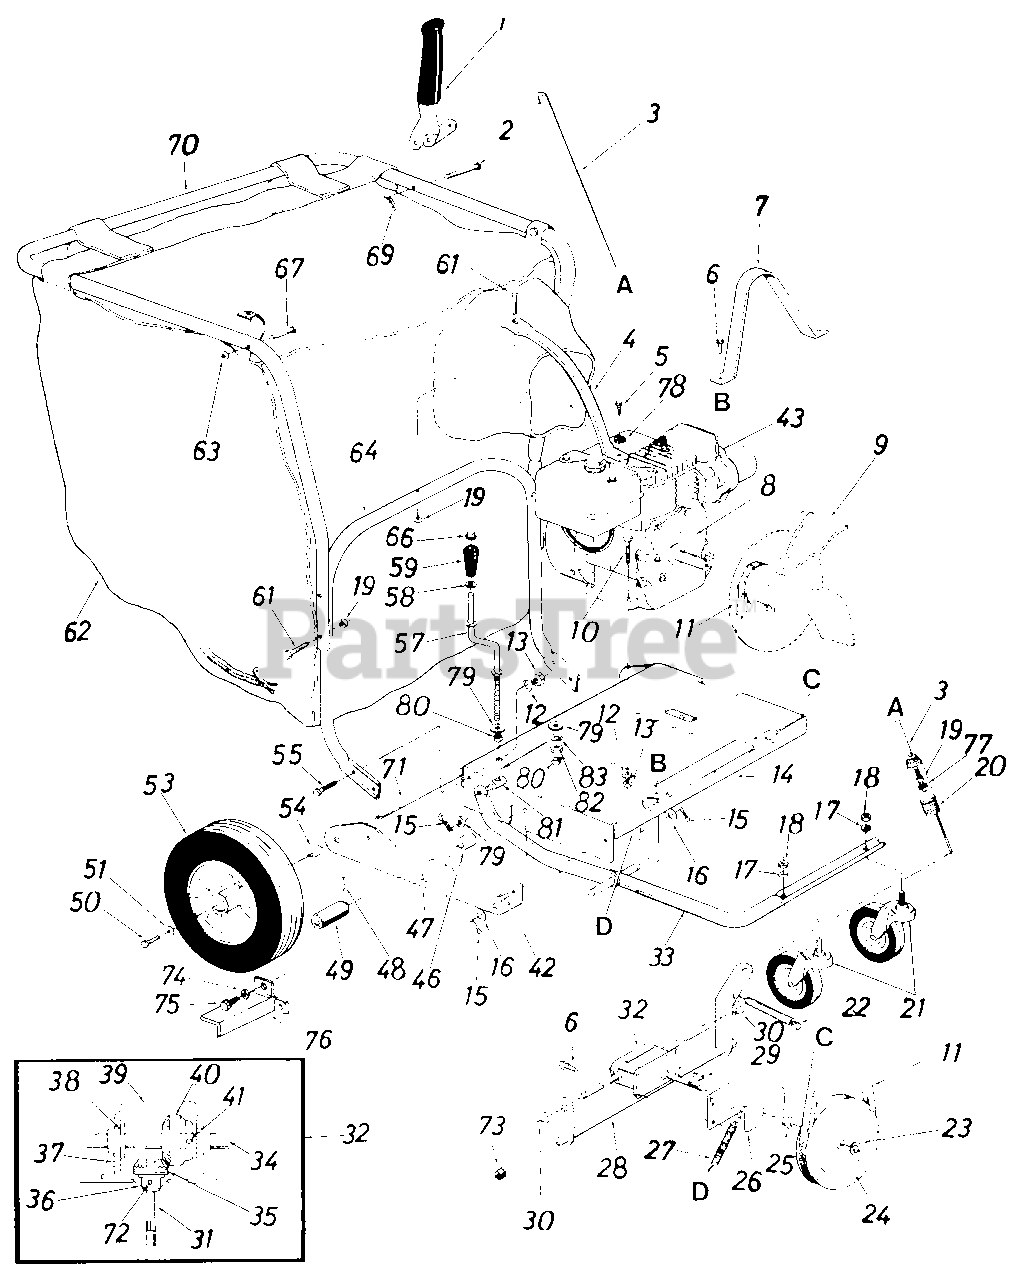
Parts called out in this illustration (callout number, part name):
1	Clutch Grip Ass y.
2	Clevis Pin .375" Dia. x 1 88"
3	Clutch Rod 32" Lg.
4	Handle Brace (Painted)
5	Part of Engine
6	Hex Wash. Hd. AB-Tap Scr. 1/4" x .62" Lg
11	"V-Belt
12	L-Wash. 5/16" I.D.
13	Hex Nut 5/16-18 Thd.*
16	Fl-Wash. .63" I.D. x 1.25" O.D.
17	L-Wash. 1/2" I.D.
18	Hex Nut 1/2-13 Thd.*
19	Hex Cent. L-Nut 1/4-20 Thd.
20	Extension Spring .78" O.D. x .75" Lg.
21	Swivel Caster Wheel 5" Dia. x 1 .25"
22	Extension Spring .38" O.D. x 7.50" Lg
23	Snap"E"-Ring.50" Dia. Shaft
24	"V"-Pulley 5/8" x 6.50" O.D.
25	Flange Bearing .502" I.D.
28	Clutch Bracket Assy zt
29	#2 Woodruff Key 3/32" Dia. x .81 " Lg.
30	Hex Flange Bearing Bronze .625" I.D.
31	Pinion Shaft .50" Dia. x 5"
32	Gear Box Ass'y. Comp.
35	Bevel Gear .50" I.D. x 14 Teeth
36	Flange Bearing .503" I.D.
37	Gear Box
38	Flange Bearing .630" I.D.
39	Gear Box Covert
40	Bevel Gear .62" I.D. x 28 Teeth
41	Spring Pin Spiral 3/16" Dia. x 1.25" Lg.
42	Hex Wash. Hd. AB-Tap Scr. 5/16" x.75" Lg.
43	Engine
46	Spacer.63" I.D. x .88" O.D. x .56" Lg.
49	Drive Piniont
50	Hex Locking Bolt 5/16-24 x .62" Lg.
51	Fl-Wash. .34" I.D. x .87" O.D.
53	Wheel Ass'y. Comp. 12" x 3"
54	Spacer .63" I.D. x 1.0" O.D. x .94" Lg.
55	Hex Bolt 5/16-18 x .75" Lg.
57	Height Adjustment Crank
58	Fl-Wash. .385" I.D. x .62" O.D.
59	Crank Knob
61	Hex Bolt 1/4-20 x 1.75" Lg.
62	Vacuum Bag-Felt
63	Push Speed Nut .25" Dia. Stud
66	Push Nut 3/8" Dia.
67	Stud Pin .250" Dia. x 1.75"
69	Internal Cotter Pin 3/8" Dia.
70	Upper Handle (Painted)
72	Spring Roll Pin 5/32" Dia. x 1.12
73	Spacer .82" I.D. x 1.0" O.D. x .305 Lg.
74	L-Wash..265" I.D.
75	Hex Self-Tap Scr. 1/4" x 3/8" Lg.
78	Belleville Washer
79	Fl-Wash. .35" I.D. x .87" O.D.
80	Spacer .38" I.D. x .50" O.D. x .18" Lg.
81	Ferrule 3/8-8 x .38" Dia.
82	Hex Nut 3/8-8 Thd.
83	L-Wash. 3/8" I.D.*
